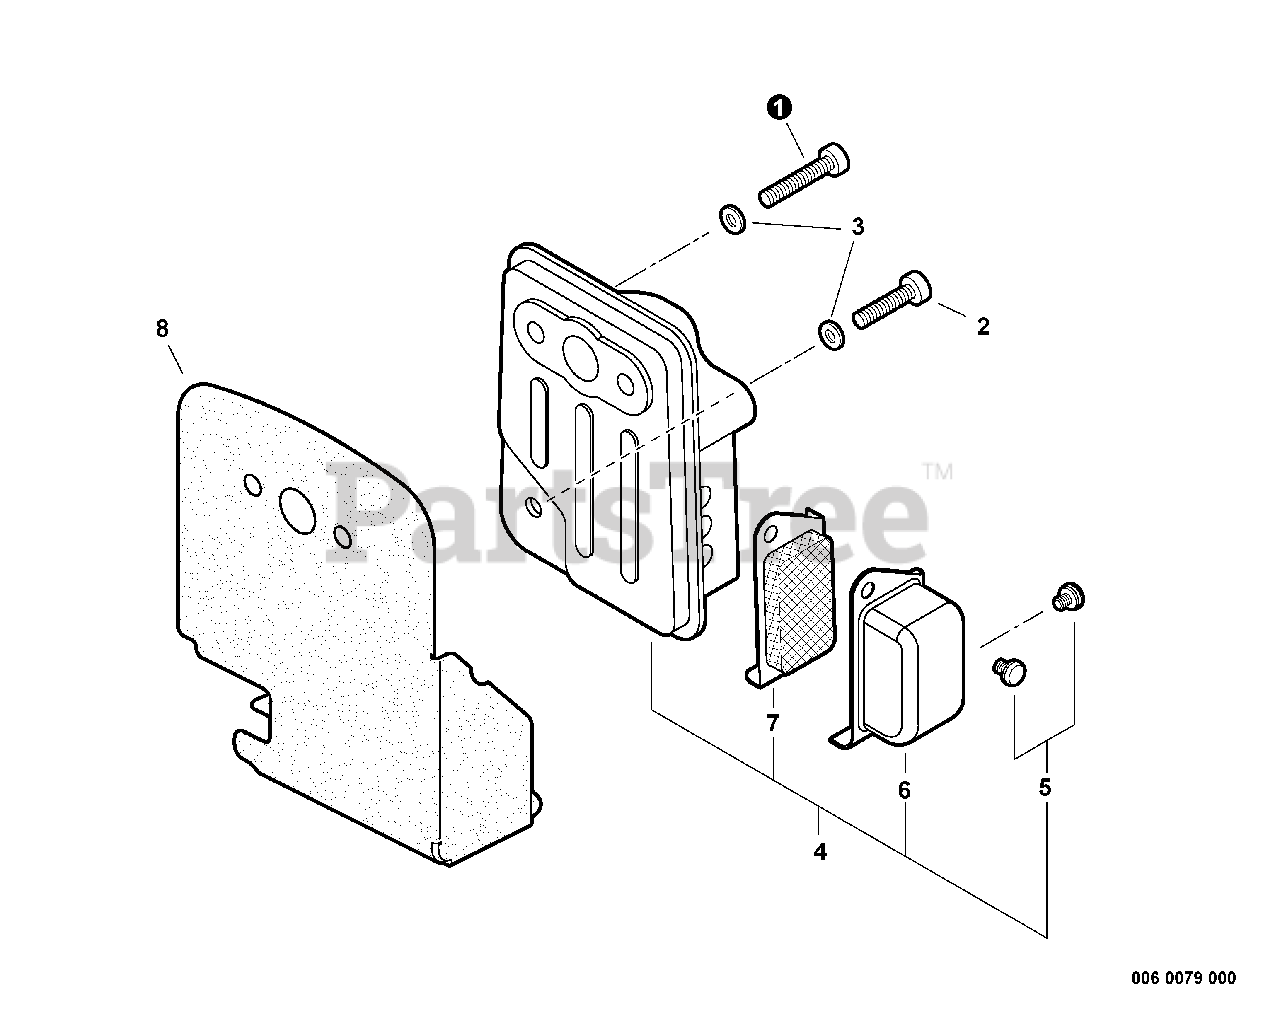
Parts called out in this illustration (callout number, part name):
1	SCREW - 5X25
2	SCREW - 5X16
3	WASHER - 5
4	MUFFLER ASSY
5	SCREW - 4X6
6	GUIDE, EXHAUST
7	SCREEN, SPARK ARRESTOR
8	SHIELD, EXHAUST
